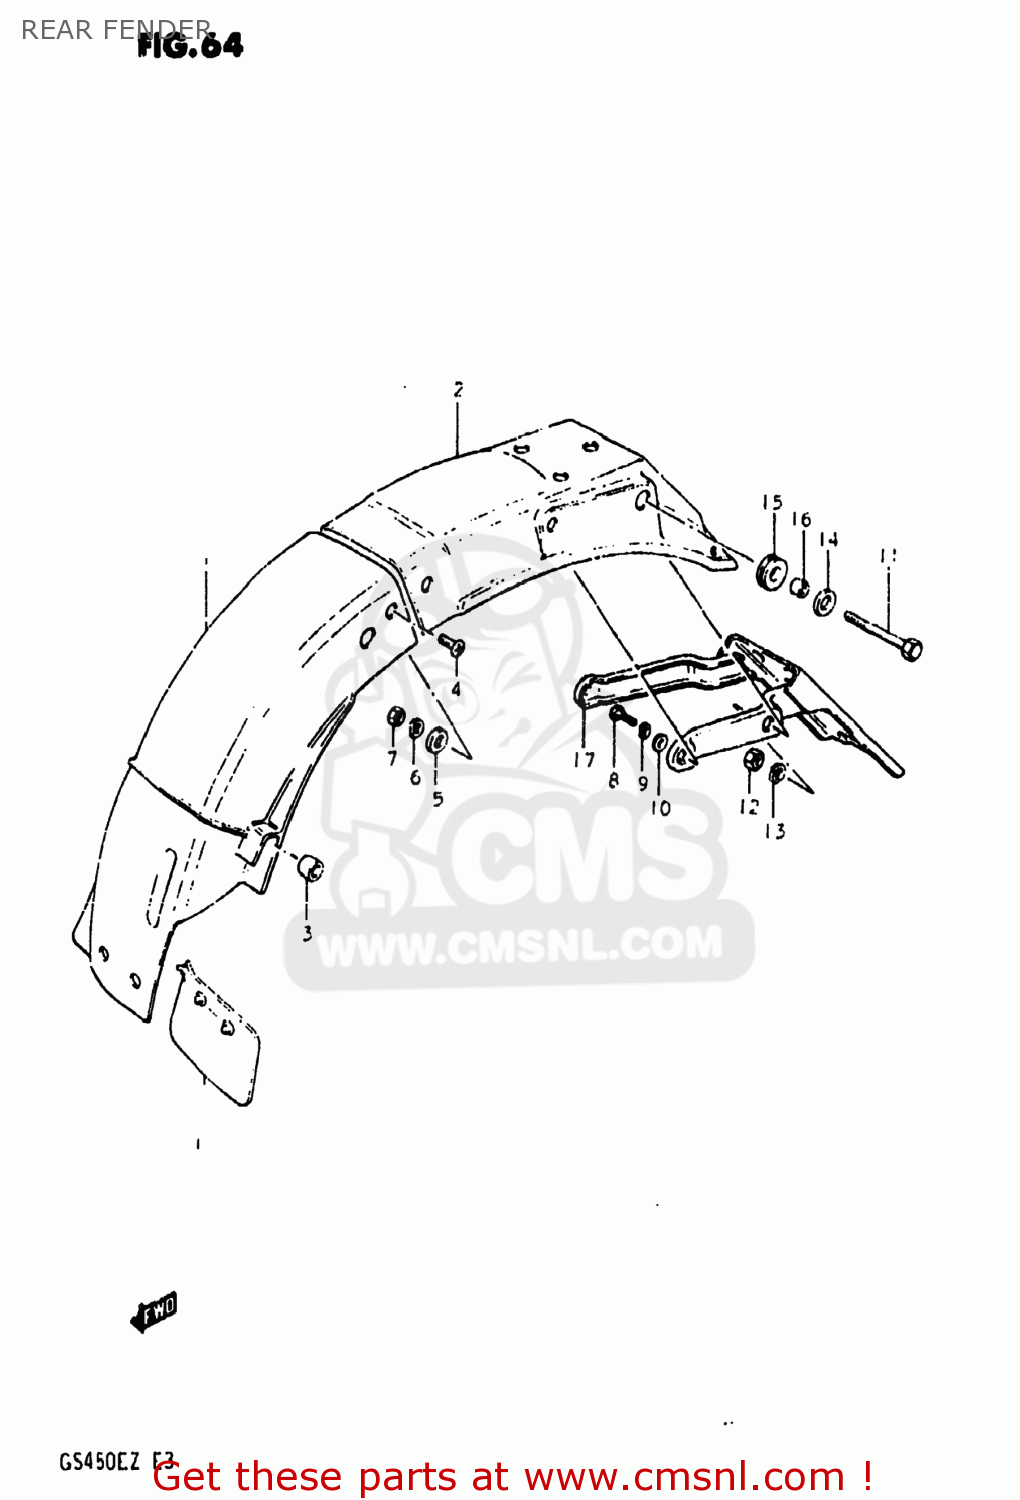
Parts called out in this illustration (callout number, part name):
1	FENDER,REAR
2	BODY,REAR FENDER,REAR
3	CUSHION
4	SCREW
5	WASHER (5.5X16X1.2)
6	LOCK WASHER
7	NUT
8	BOLT, UPPER
9	LOCK WASHER
10	WASHER
11	BOLT
12	NUT
13	LOCK WASHER
14	WASHER(8.5X26X1.2)
15	CUSHION
16	SPACER (8.2X12X7.5)
17	REINFORCEMENT,REAR FENDER
18	GUIDE,RR FENDER MUD
